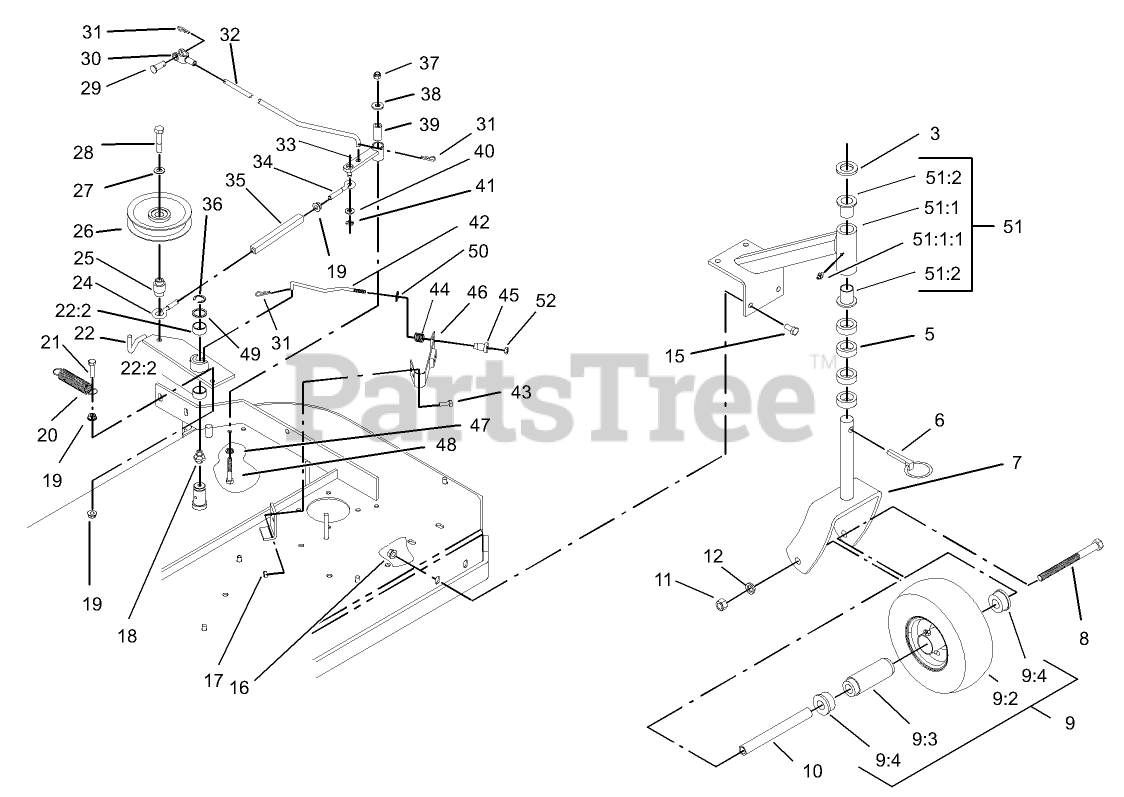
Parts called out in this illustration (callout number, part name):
3	WASHER-FLAT
5	SPACER-CASTER
7	FORK
8	SCREW-HH
9	WHEEL AND TIRE ASM
9:3	BEARING
9:4	BUSHING
10	SPACER
11	NUT-HH
12	WASHER-LOCK
15	SCREW-HH
16	NUT-HHF, WHIZ
17	NUT-LOCK, NI
18	FITTING-GREASE
19	NUT-HF
20	SPRING-EXTENSION
21	SCREW-HH
22	Idler Arm ASM
22:2	SLEEVE-BEARING
24	EYEBOLT-THREAD, LH
25	BUSHING-ENGAGEMENT
26	PULLEY-IDLER
27	WASHER-BELLEVILLE
28	SCREW-HH
29	PIN-CLEVIS
30	YOKE-ADJUSTABLE
31	PIN-COTTER
32	ARM-ASSIST, LINKAGE
33	ARM-ASSIST
34	EYEBOLT-THREAD, RH
35	BODY-TURNBUCKLE
36	RING-RETAINING, EXT
37	NUT-LOCK, NI
38	WASHER-FLAT
39	TUBE-PIVOT
40	WASHER-PLAIN
41	RING-RETAINING, EXT
42	ROD-BRAKE
43	SCREW-HH
44	SPRING-COMPRESSION
45	SPACER-FLANGED
46	PAD AND SPRING ASM
47	WASHER-SPRING
48	SCREW-HH
49	WASHER-SPINDLE
50	RING-PUSH ON
51	SUPPORT ASM
51:1	Support-Caster
51:1:1	FITTING-GREASE
51:2	BEARING-FLANGED
52	NUT-LOCK, NI
